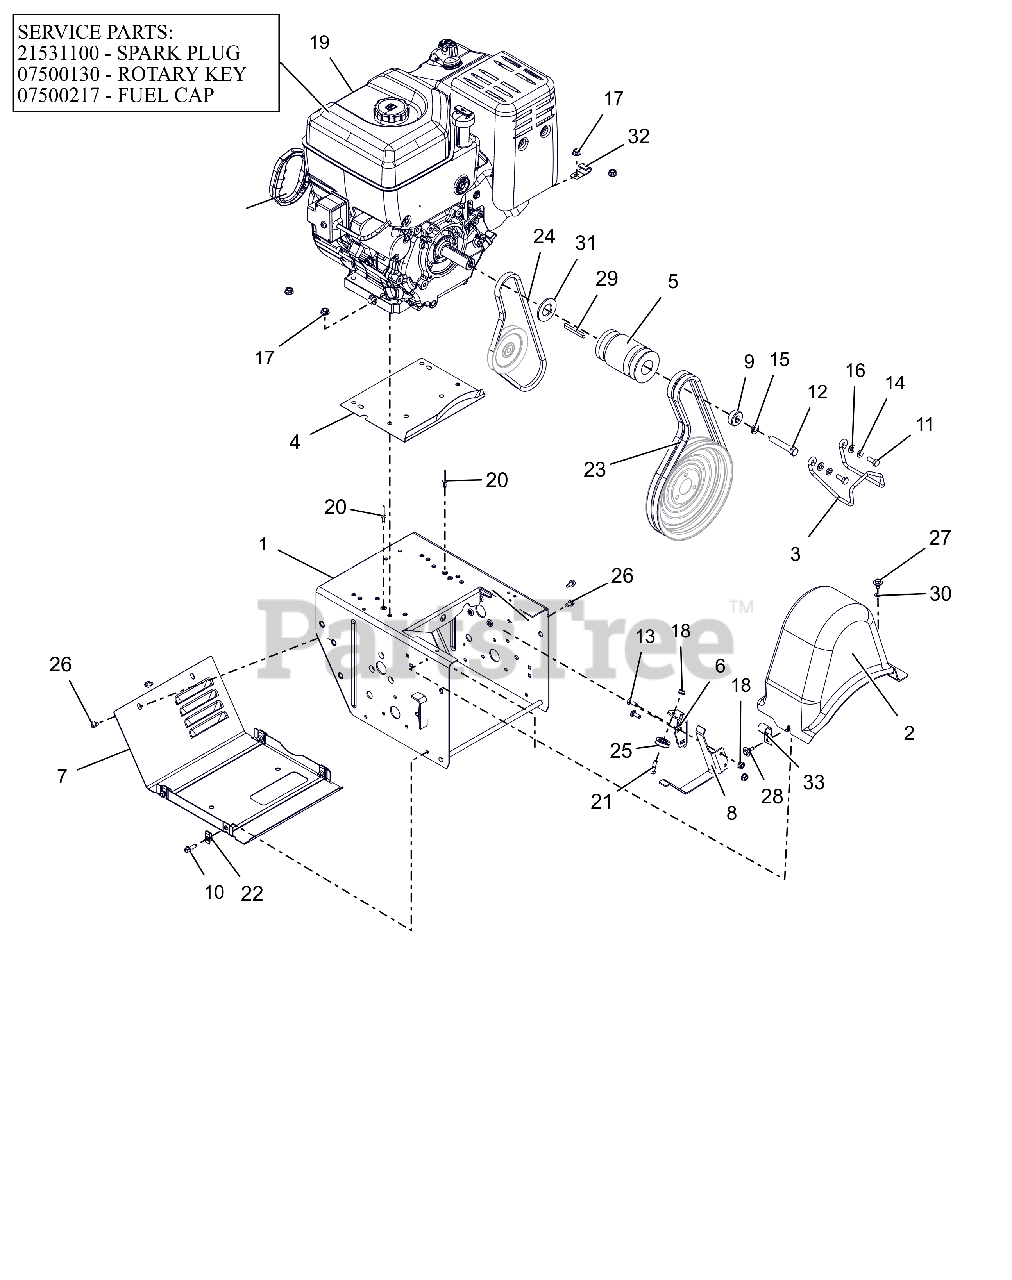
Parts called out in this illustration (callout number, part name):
1	FRAME, MAIN - PRO (WELDMENT)
2	COVER, BELT-LARGE
3	FINGER, BELT
4	BAFFLE, WATER - LARGE BLOCK
5	SHEAVE, COMBO HYDRO WHEEL 4L
6	BRACKET, CLUTCH CABLE
7	COVER, BOTTOM - VENTILATED
8	FINGER, BELT - FLAT
9	BSHG-SPACER .47X1.25X.50
10	BLT-HEX .25-20X.75 HWH YZ GR5
11	BLT-HEX .31-24X.75 YWZC GR5
12	BLT-HEX .44-20X2.50 GR5 YWZC
13	@BLT-RDHDSQNK .25-20X.75 G5YZ
14	WSHR-LK .312X.097 HVY YWZC
15	@WSHR-LK .44X.109 REG YWZC
16	@WSHR-FL-STL.344X.688X.065YWZC
17	@NUT-LK-CTR-FLG .31-18 YZ GR F
18	@NUT-LK-TOP-FLG .25-20 YWZC
19	ENGINE, BRIGGS PF 2100, 12V
19	PLUG, SPARK 20HP B&S VANGUARD
19	KEY, IGNITION ROTARY B&S
19	CAP, FUEL - BRIGGS & STRATTON
20	RVT-POP .187 YZ
21	BOLT, SHLDR-.375X.375X.25-20
22	NUT-RTNR .25-20X.56
23	V-BELT, HA-RAW EDGE (SET)
24	V-BELT, 4L-WRAPPED
25	PULLEY, CABLE
26	SCR-TAP .25-20X.50 HWH TR YWZ
27	SCR-TAP .25-20X.50 LGHWH TR YZ
28	SCR-TAP .25-20X.5 CAPTIVE
29	KEY, SQ .248/.246 X 2.25
30	NUT-PUSH .25X.50 O.D.
31	WSHR-FL-STL- 1.062X2.0X.134 YZ
32	J-CLAMP
33	J-CLAMP
